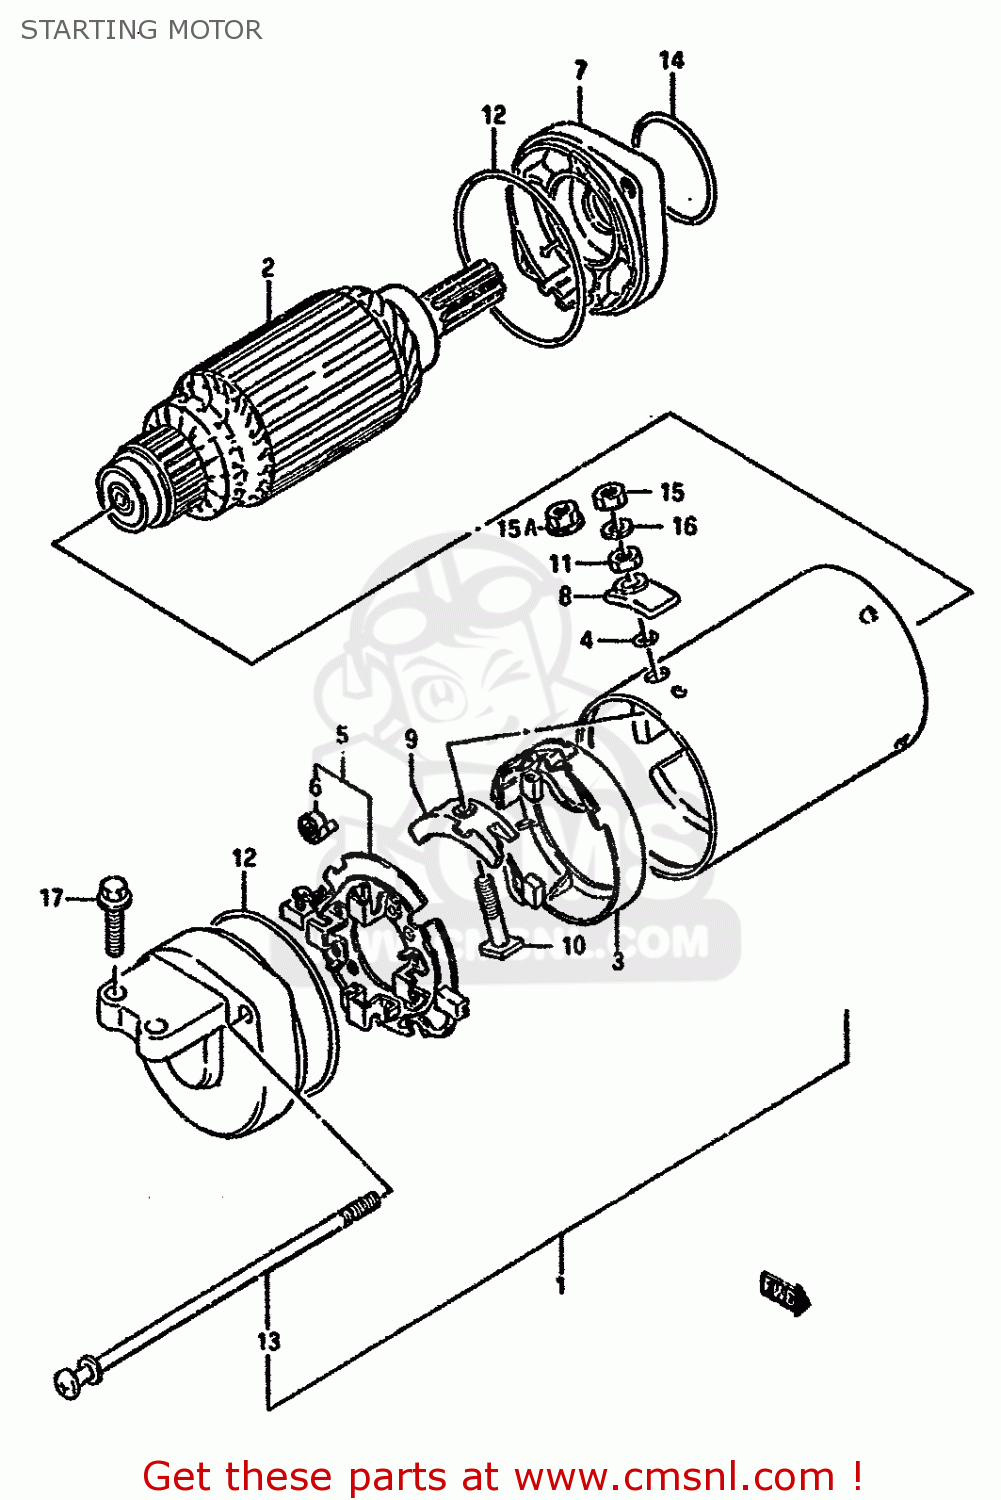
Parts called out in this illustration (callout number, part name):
1	MOTOR ASSY ,STARTING
2	ARMATURE
3	TERMINAL SET,BRUSH
4	O RING
5	HOLDER SET,BRUSH(-)
6	SPRING
7	HOUSING ASSEMBLY,STARTER
8	BUSHING
9	BUSHING
10	BOLT
11	NUT
12	O RING
13	BOLT
14	O-RING (D:2.0)
15	NUT
15A	NUT
16	WASHER,LOCK
17	BOLT
